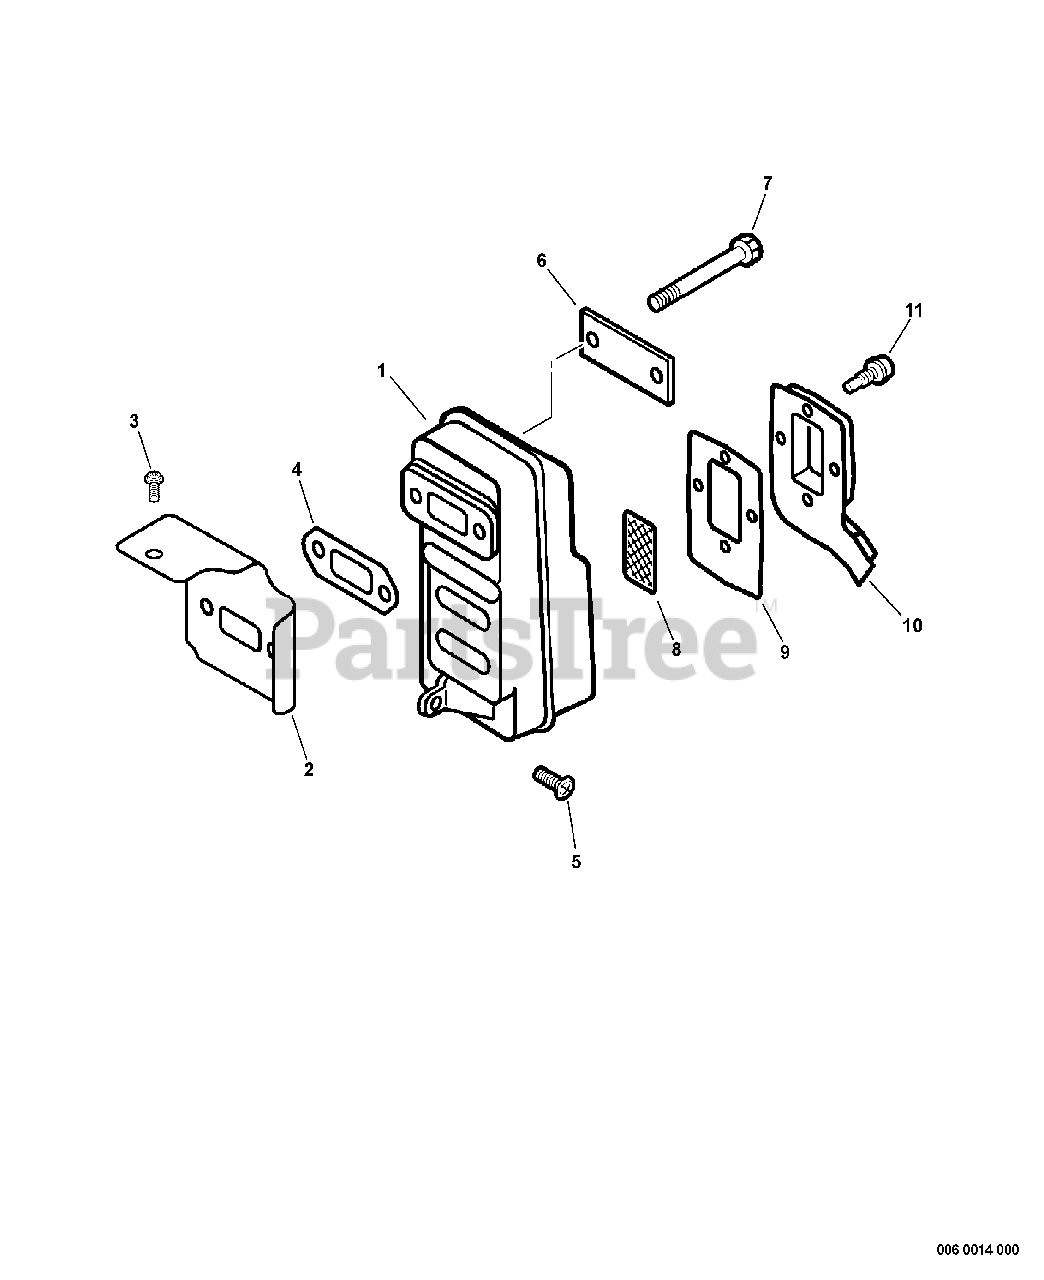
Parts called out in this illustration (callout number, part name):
1	MUFFLER
2	COVER, CYLINDER - EXHAUST
3	SCREW - 5X10
4	GASKET, EXHAUST
5	SCREW - 5X20
6	PLATE
7	BOLT
8	SCREEN, SPARK ARRESTOR
9	GASKET, EXHAUST
10	GUIDE, EXHAUST
11	SCREW - 4
